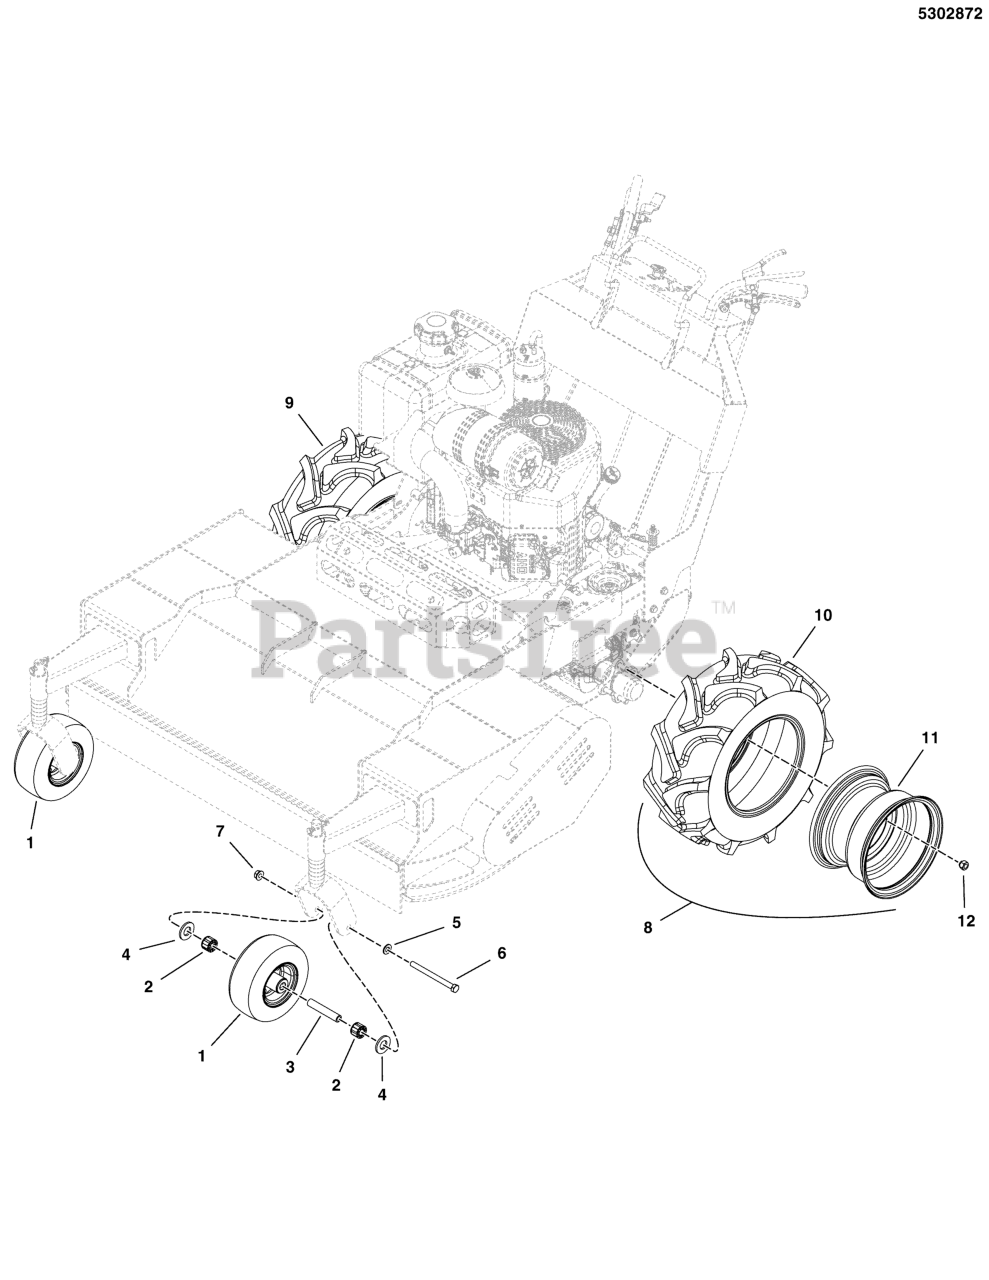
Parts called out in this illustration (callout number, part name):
1	FLAT FREE TIRE ASSY, 9.00 X 3.50 - 4.00
2	BEARING
3	AXLE, CASTER WHEEL
4	RETAINER, BEARING
5	WASHER, 1/2 SAE
6	BOLT, 1/2-13 X 6 GD5 YZ
7	NUT, Hex Flange, Nylock, 1/2-13
8	TIRE ASM, 20X8.00-10, LH, LUG BAR
9	TIRE ASM, 20X8.00-10, RH, LUG BAR
10	TIRE, 20 X 8.00-10, LUG BAR
11	WHEEL, 10X7.00 4/4 SOLID F237 2.625 OS
12	NUT, 1/2-20, FOR WHEEL BOLT SILVER
